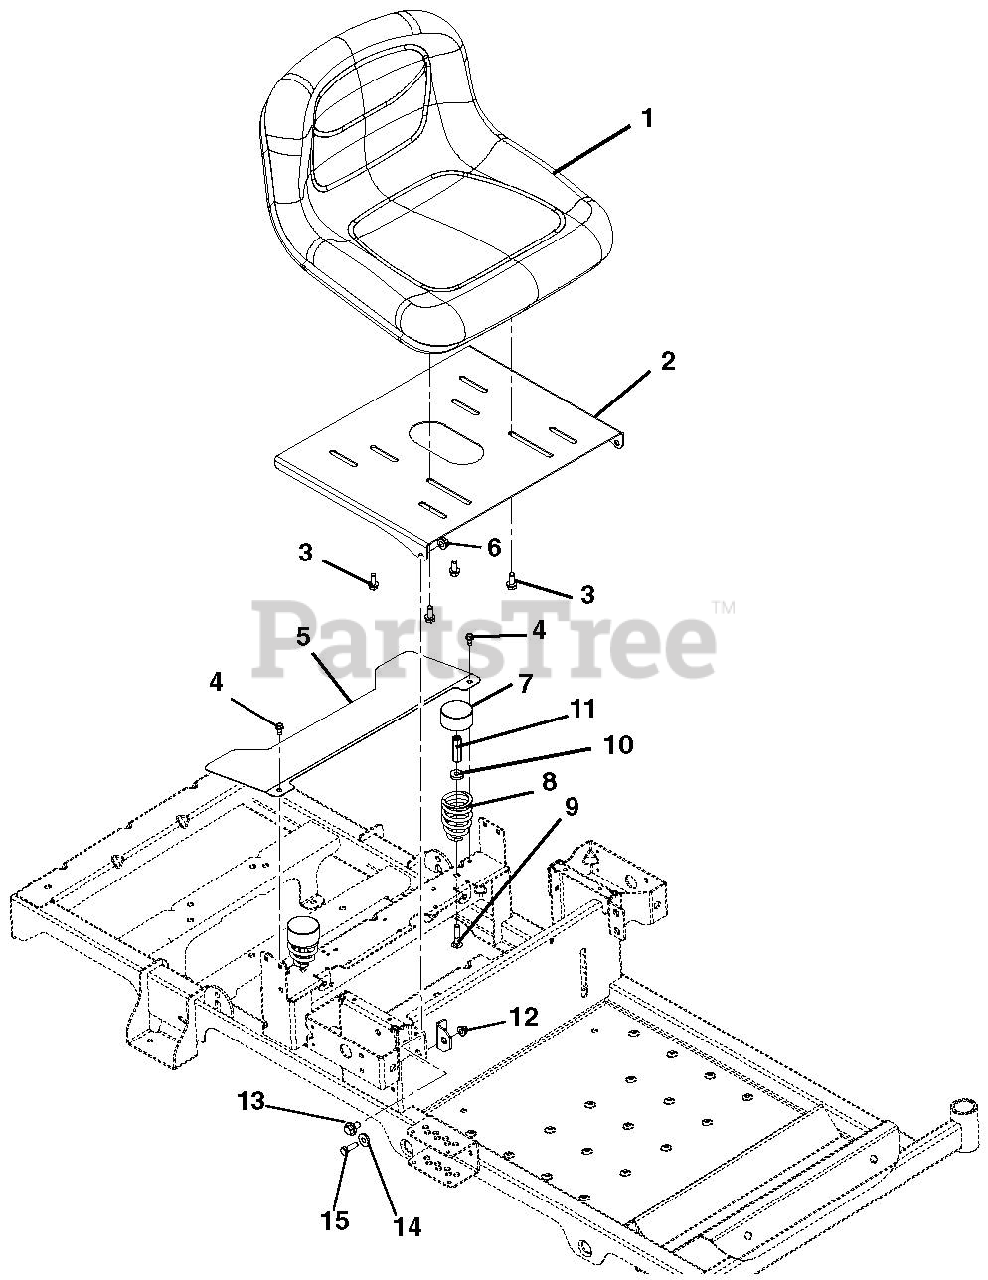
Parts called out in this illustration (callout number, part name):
1	SEAT-13" GREY
2	PLATE, SEAT
3	5/16-18X3/4 HX/W/HD WHIZ
4	@SCR-TAP .25-20X.50 HWH TR YWZ
5	PLATE, FAN GUARD
6	@NUT-LK-TOP-FLG .38-16 YWZC
7	HUB CAP
8	SPRING, SEAT
9	@BLT-RDHDSQNK .31-18X1.50 G5YZ
10	WSHR-FL-STL .328X.87X.179 YWZC
11	NUT, COUPLING 5/16-18 X 1 3/4
12	@NUT-LK-NYL-FLG .31-18 YWZC
13	BOLT-SHLDR .375-16X.150
14	BSHG, FLG .325X.499X.26X.88
15	@BLT-HEX .31-18X1.00 GR5 YWZC
